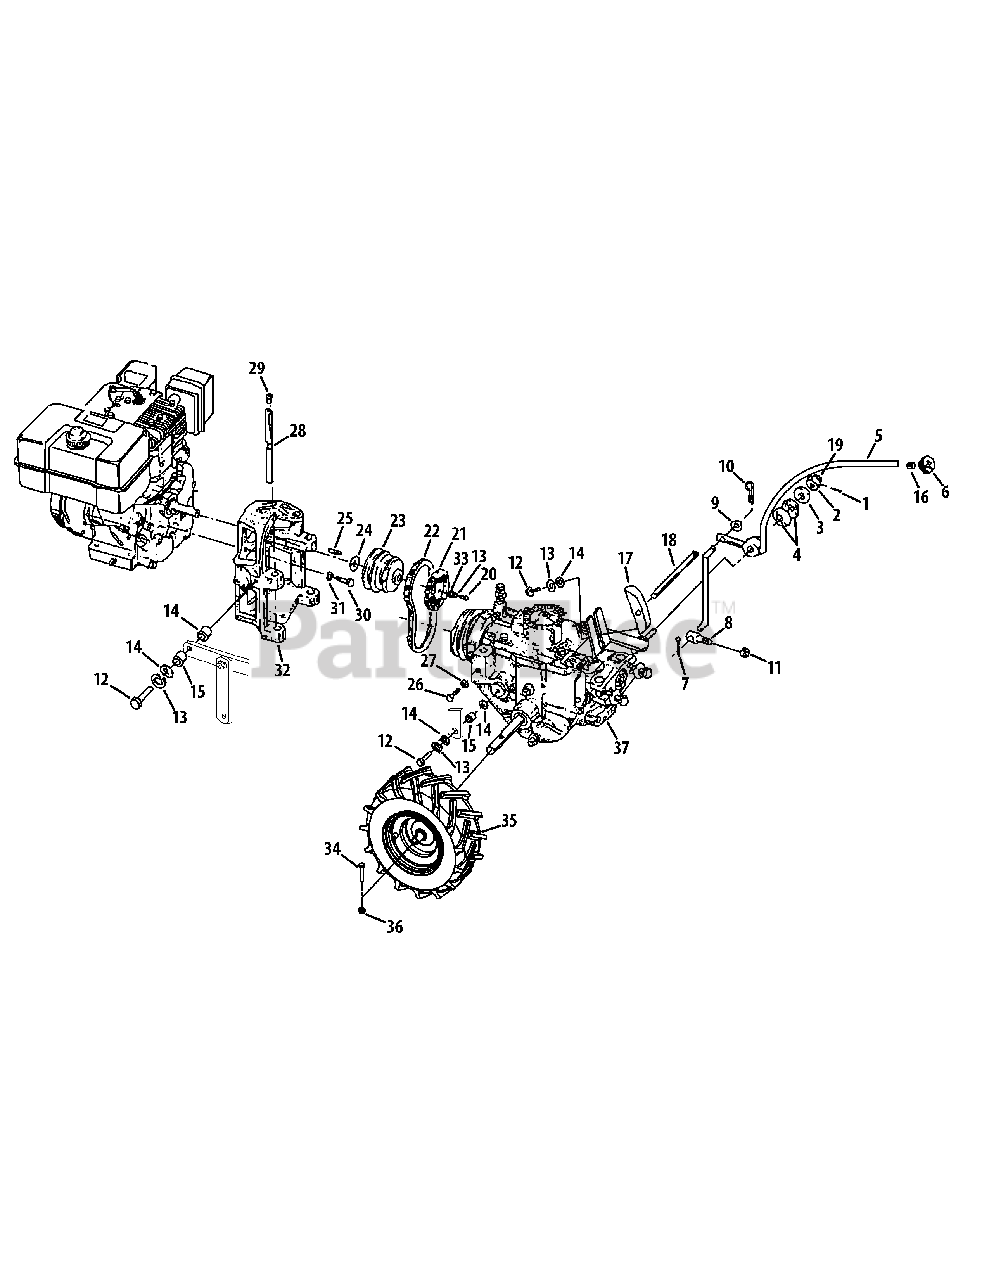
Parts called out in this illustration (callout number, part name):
1	Spring Pin, 1/8"
2	Flat Washer, .510 x 1.0 x .125
3	Shoulder Washer, 1.25 x .50 x .25
4	Disc Spring Washer
5	Wheel Speed Shift Lever
7	Cotter Pin, 3/32" x 1"
9	Flat Washer, .344 x .688 x .065
10	Hair Pin Cotter
11	Hex Locknut, 5/16"-18
12	Hex Head Screw, 3/8"-16 x 1"
13	Lockwasher, 3/8"
14	Flat Washer, .406 x .810 x .051
15	Bushing Spacer, .5 x .375 x .3
16	Retaining Ring
17	Belt Adjustment, 3-7/8"
18	Belt Adjustment Rod
19	Hex Nut, 1/2"-20
20	Hex Head Screw, 3/8"-24 x 1.75
21	Reverse Disc
22	Forward Drive Belt
23	Engine Power Take-off Pulley
24	Flat Washer, .766 x 1.0 x .031
24	Flat Washer, .766 x 1.0 x .062
25	Engine Pulley Key, 3/16"x 2-1/2"
26	Hex Head Screw, 5/16"-18 x 1"
27	Hex Nut, 5/16"-18
28	Engine Mounting Bar
29	Thread Protector Plug
30	Hex Head Screw, 5/16-24 x 1.25
31	Lockwasher, 5/16"
33	Flat Washer, .406 x 1.0 x .105
34	Hex Screw, 1/4"-20 x 1-1/2"
35	Wheel Assembly, 16 x 4.6 x 8"
35	Tire, 16.2 x 4.6
36	Hex Flange Nut, 1/4"-20
37	Clutch Bracket
